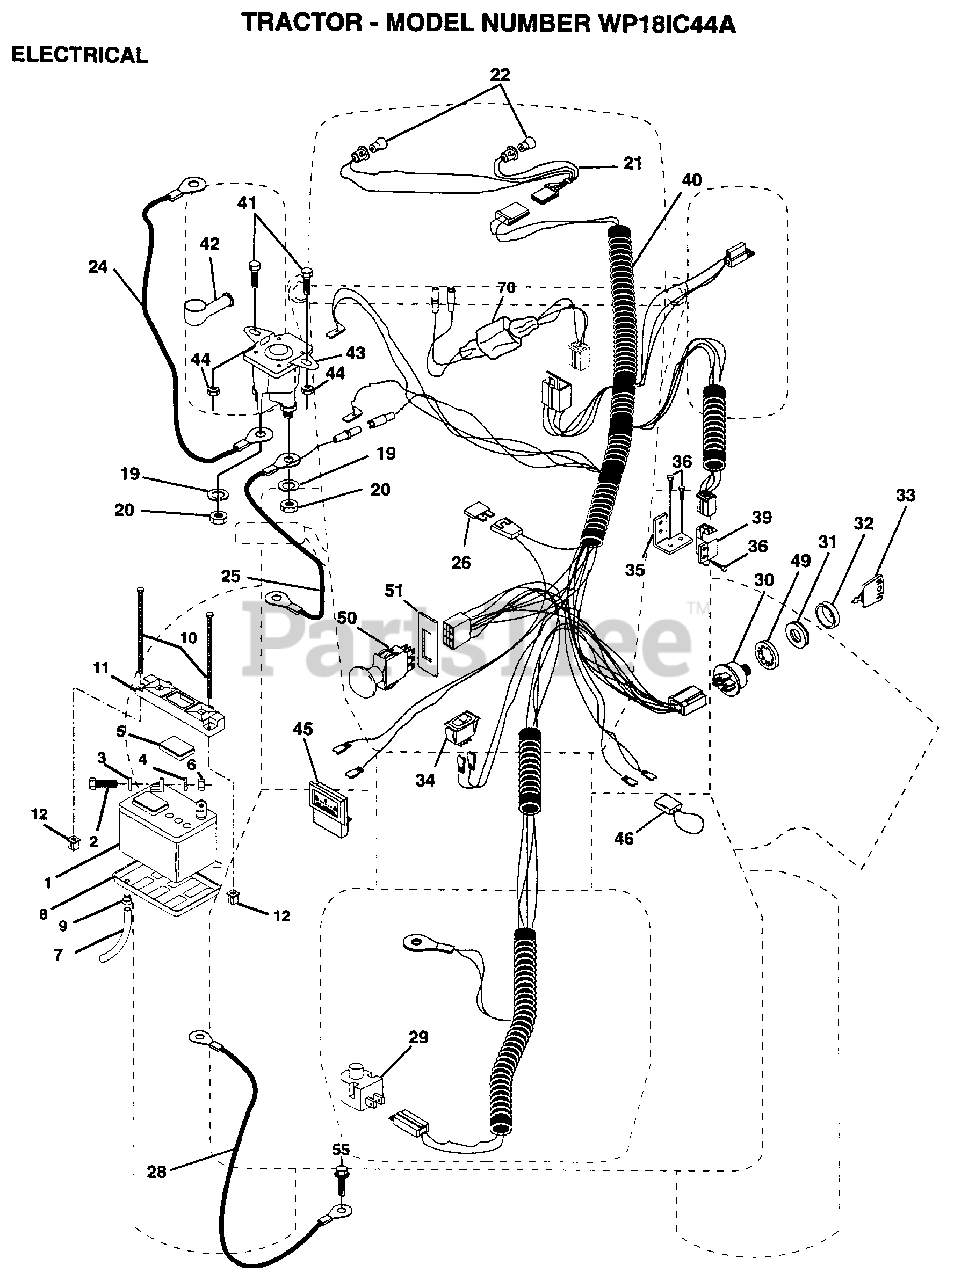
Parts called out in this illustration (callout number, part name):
2	BOLT LT
3	WASHER
4	LOCKWASHER
5	"CAP,BATTERY "
7	"DRAIN TU T, BATT"
8	"TRAY T, BATTERY"
9	HOSE CLAMP T
20	NUT
21	"HARNESS,LIGHT SOC"
22	HEADLAMP BULB
24	"CABLE T, BATTERY"
25	CABLE.6GA.22W/16W
26	FUSE HYT
28	CABLE.GRND.6GA.21
29	SWITCH SEAT
32	COVER KEY SWITCH
33	KEY MLD GEN DELTA
34	SWITCH LT
35	BRACKET LT
36	SCREW
39	SWITCH INTERLOCKT
40	HARNESS.ING.ELEC.
41	BOLT.HX.1/4-20
44	NUT
46	PROTECTION LOOP
49	LOCKWASHER
51	RING RETAIN PTO
55	SCREW LT
70	HARN.ENG.TRI-CKT
